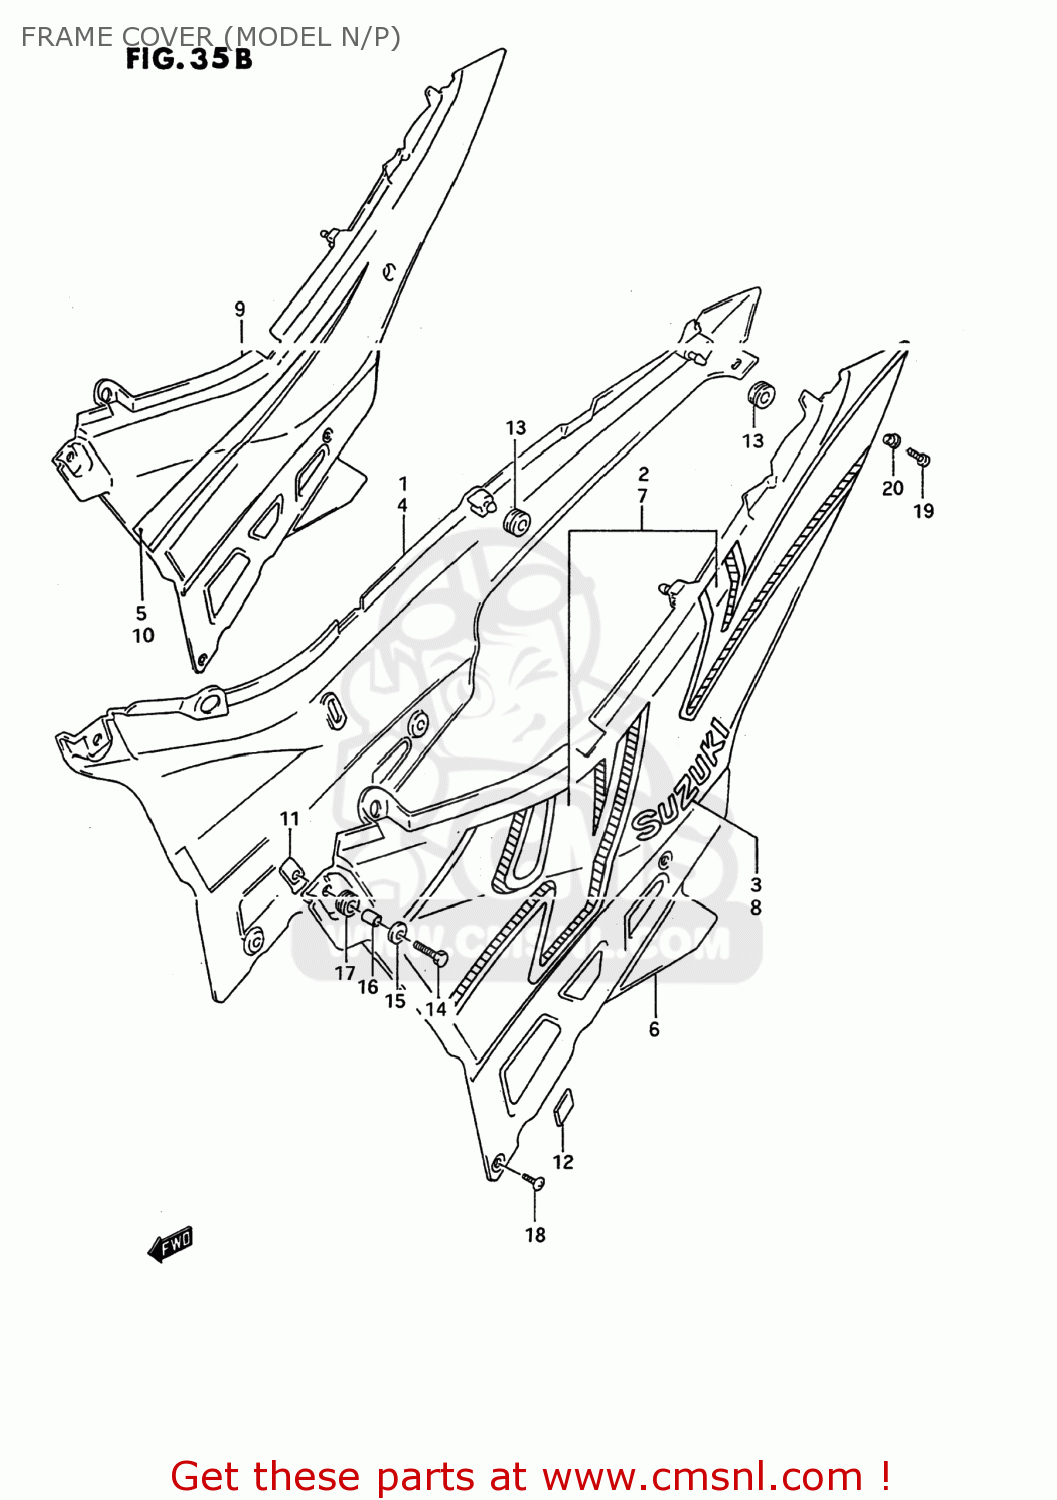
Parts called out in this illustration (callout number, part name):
1	COVER,FRAME,RIGHT
2	TAPE SET,FRAME COVER STRIPE
3	EMBLEM,FRAME COVER
4	COVER,FRAME,R
5	TAPE,FRAME COVER STRIPE
6	COVER,FRAME,LEFT
7	TAPE SET,FRAME COVER STRIPE
8	EMBLEM,FRAME COVER
9	COVER COMP,FRAME,LEFT
10	TAPE,FRAME COVER STRIPE
11	PLATE,FRAME COVER
12	CUSHION,FRAME COVER
13	CUSHION
14	BOLT(6X20)
15	WASHER
16	SPACER (6.1X9X9)
17	CUSHION
18	SCREW(5X15.3)
19	SCREW, FRONT & REAR
20	WASHER
